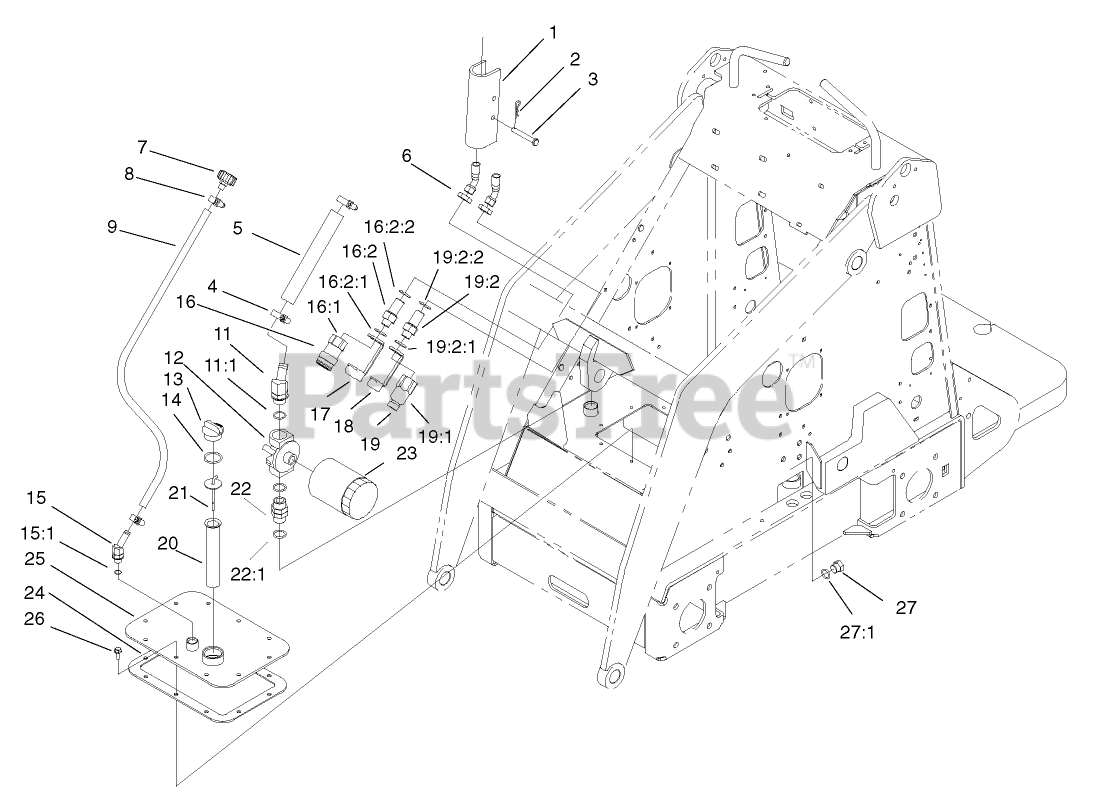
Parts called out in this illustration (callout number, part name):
1	LOCK-CYLINDER
2	PIN-HAIR
3	PIN-CLEVIS
4	CLAMP-HOSE
5	HOSE-SUCTION, HYD
6	NUT-LOCK, BULKHEAD
7	BREATHER
8	CLAMP-HOSE
9	HOSE-VENT
11	ELBOW-45 DEG
11:1	O-RING
12	HEAD-FILTER
13	PLUG-PLASTIC
14	O-RING
15	FITTING-HYD, 45 DEG
15:1	O-RING
16	Bulkhead Coupler ASM
16:1	COUPLER-FACE, FLUSH
16:2	FITTING-ADAPTER, BULKHEAD
16:2:1	O-RING
16:2:2	O-RING
17	CAP-DUST, NIPPLE
18	CAP-DUST, COUPLER
19	BULKHEAD NIPPLE ASM
19:1	NIPPLE-FACE, FLUSH
19:2	FITTING-ADAPTER, BULKHEAD
19:2:1	O-RING
19:2:2	O-RING
20	FILTER-SCREEN
21	DIPSTICK-OIL
22	FITTING-THREAD, STRAIGHT
22:1	O-RING
23	FILTER-OIL, TRANSMISSION
24	GASKET-COVER
26	SCREW
27	PLUG-HEX
27:1	O-RING
